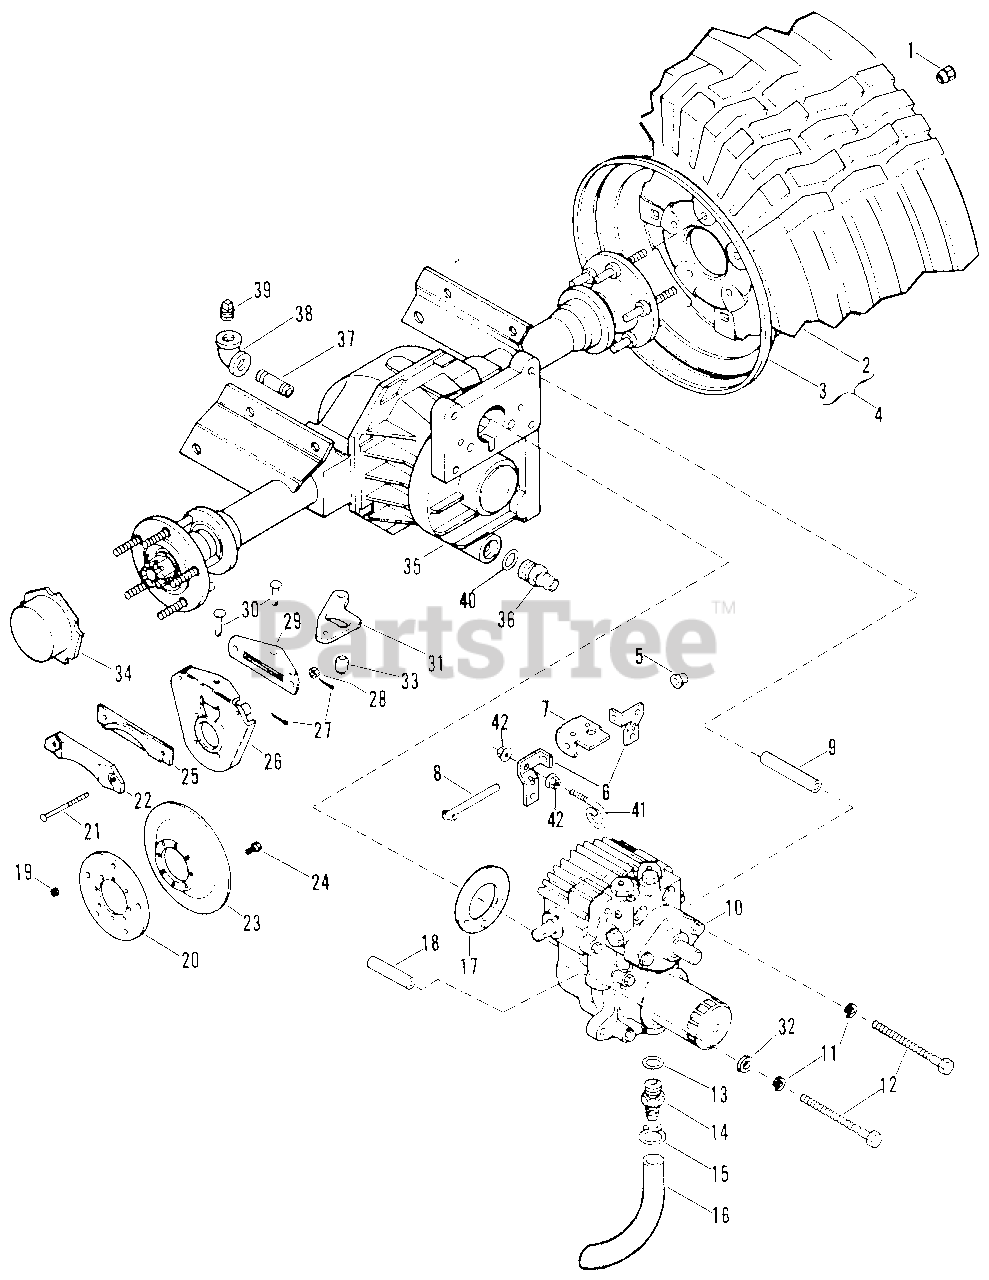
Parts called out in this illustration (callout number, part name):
1	Nut, Lug 7/16-20
2	Tire
3	Rim
4	Assembly, Rear Tire 10.50 x 23
5	Nut
6	Support
7	Cam
8	Pivot Rod
9	Spacer
10	Transmission Assembly
11	Washer, Lock 3/8 Reg.
12	Screw, Cap 3/8-16 x 5"
13	O-Ring, 3/4 Nom. I.D.
14	Connector
15	Clamp, Hose
16	Hose
17	Gasket
18	Spacer
19	Grommet
20	Carrier
21	Bolt, 3/8-16 x 3.50 Rd Hd Sq Nk
22	Caliper Plate
23	Disc
24	Screw, Taptite 1/4-20 x 3.75
25	Friction Plate
26	Caliper Mounting Plate
27	Pin, Cotter .09 x .75
28	Nut, Lock 3/8-16
29	Pressure Plate
30	Pin
31	Brake Arm
32	Washer, Flat .38 x .75 x .125
33	Roller
34	Rear Hub Cap
35	Rear Axle and Supports
36	Connector
37	Pipe Nipple 1/2 x 2
38	Elbow 1/2 x 90
39	Pipe Plug
40	O-Ring, .924 Nom. I.D.
41	Support, Cable
42	Nut, Flange Whiz-Lock 1/4-20
NS	Transmission Decal
